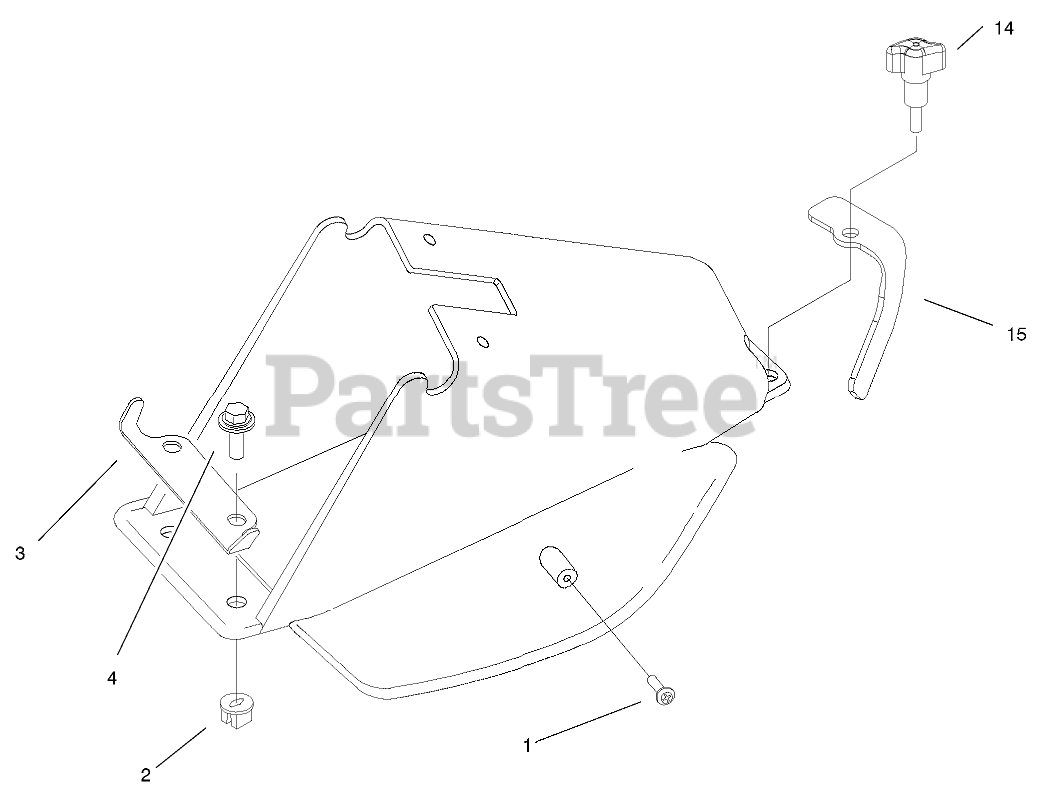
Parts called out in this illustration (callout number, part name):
1	SCREW-PPH
2	NUT - CLIP
3	BRACKET-MOUNT,CHUTE
4	SCREW-HWH
15	CLAMP-DOOR
